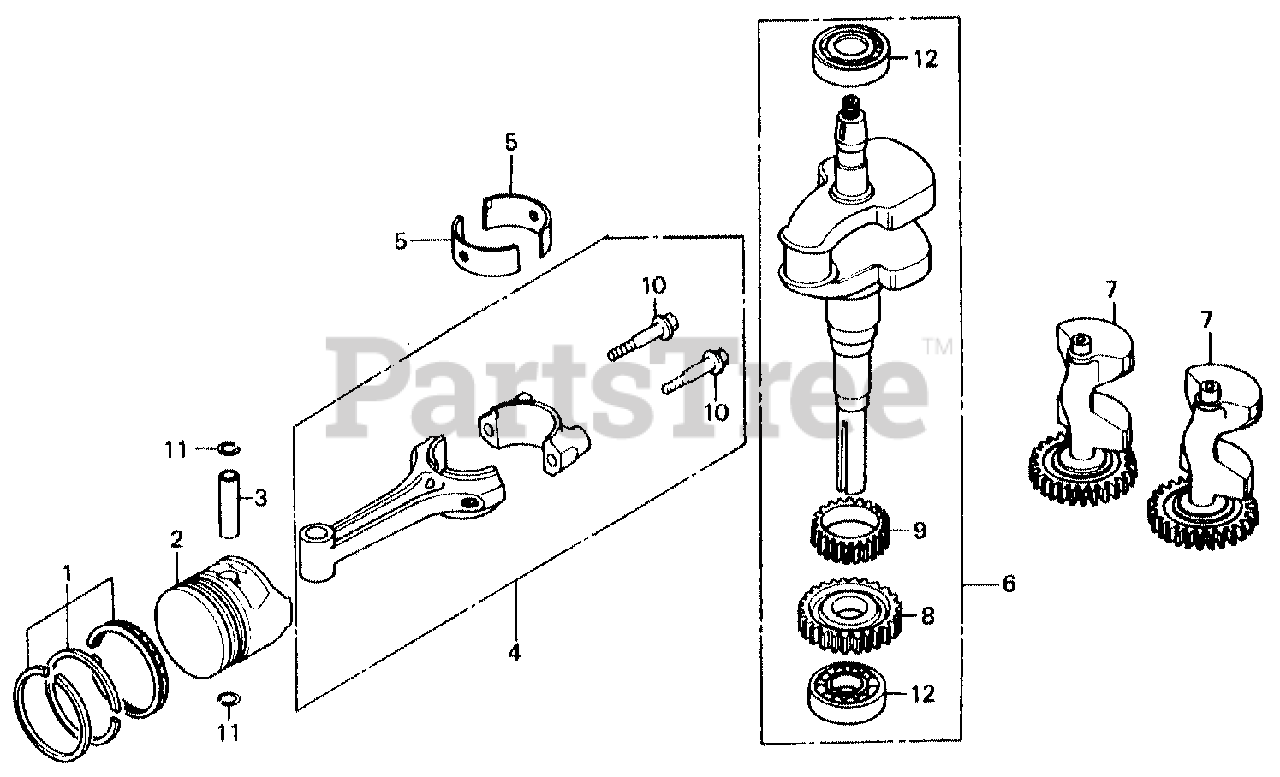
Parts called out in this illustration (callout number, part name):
1	RING SET, PISTON (STD)
1	RING SET, PISTON (STD) (NOT AVAILABLE)
1	RING SET, PISTON (OS 0.25)
1	RING, PISTON (OS 0.50)
1	RING SET, PISTON (OS 0.50) (NOT AVAILABLE)
1	RING SET, PISTON (0.75) (NOT AVAILABLE)
2	PISTON (STD)
2	PISTON (OS 0.25)
2	PISTON (OS 0.50)
2	PISTON (0.75)
3	PIN, PISTON
4	ROD ASSY., CONNECTING
5	BEARING A, CONNECTING ROD (BLACK)
5	BEARING B, CONNECTING ROD (BROWN)
5	BEARING C, CONNECTING ROD (GREEN)
5	BEARING D, CONNECTING ROD (YELLOW)
5	BEARING E, CONNECTING ROD (PINK)
6	CRANKSHAFT
7	WEIGHT, BALANCER
8	GEAR, BALANCER
9	GEAR, TIMING
10	BOLT, CONNECTING ROD (8MM)
11	CLIP, PISTON PIN (19MM)
12	BEARING, RADIAL BALL (6206)
